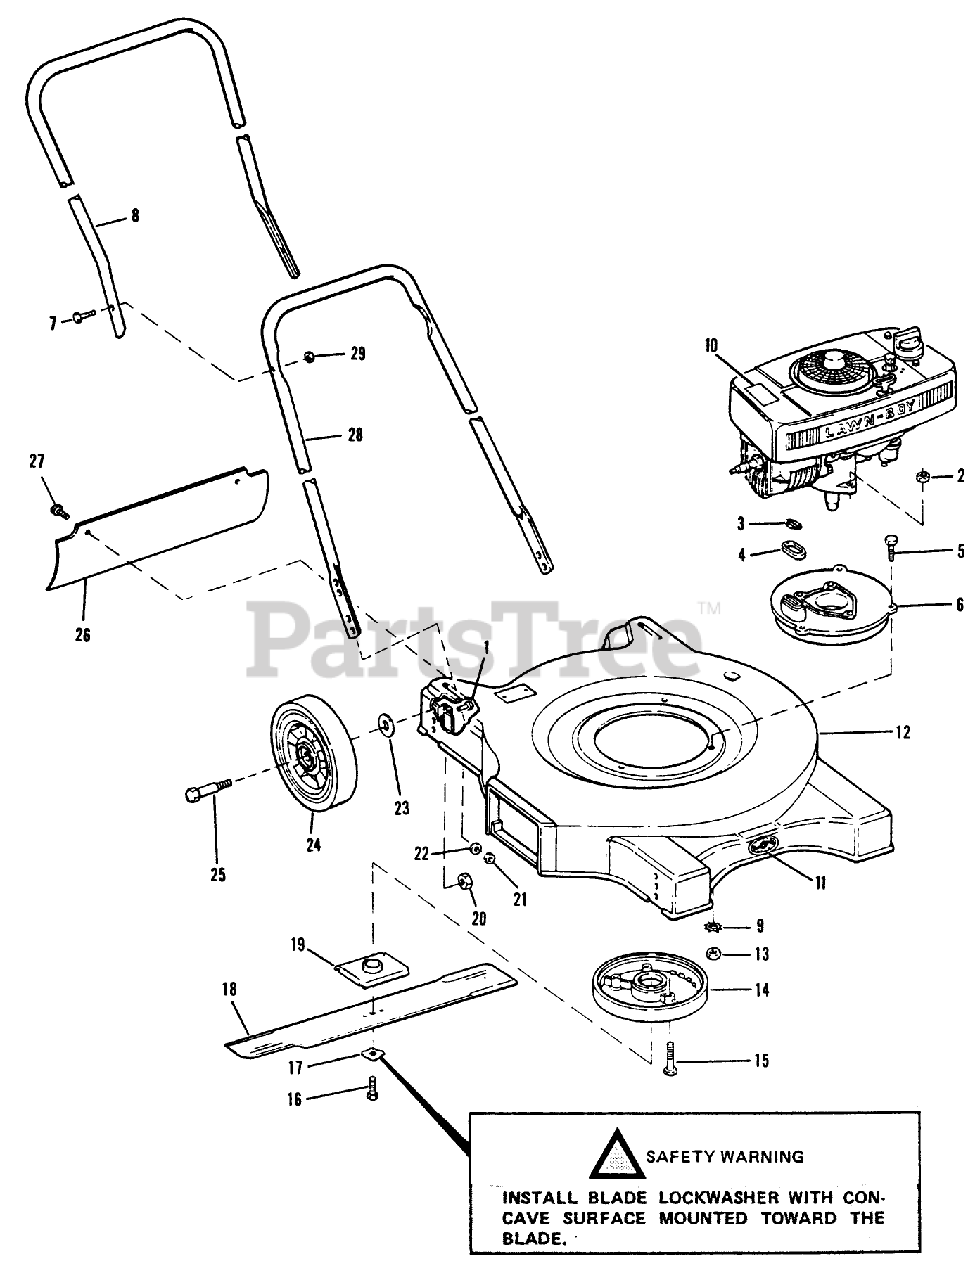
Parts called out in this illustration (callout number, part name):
1	Harness, Wire
2	NUT-LOCK F
4	GASKET S
6	Muffler-Top Half
9	Lockwasher
12	Housing
13	NUT-LOCK F
14	Muffler-Bottom Half
15	Bolt-Muffler
17	LOCKWASHER
20	LOCKNUT
21	LOCKNUT E
23	WASHER-PLAIN
24	WHEEL&TIRE ASSY
28	Cover Plate
29	LOCKNUT E
